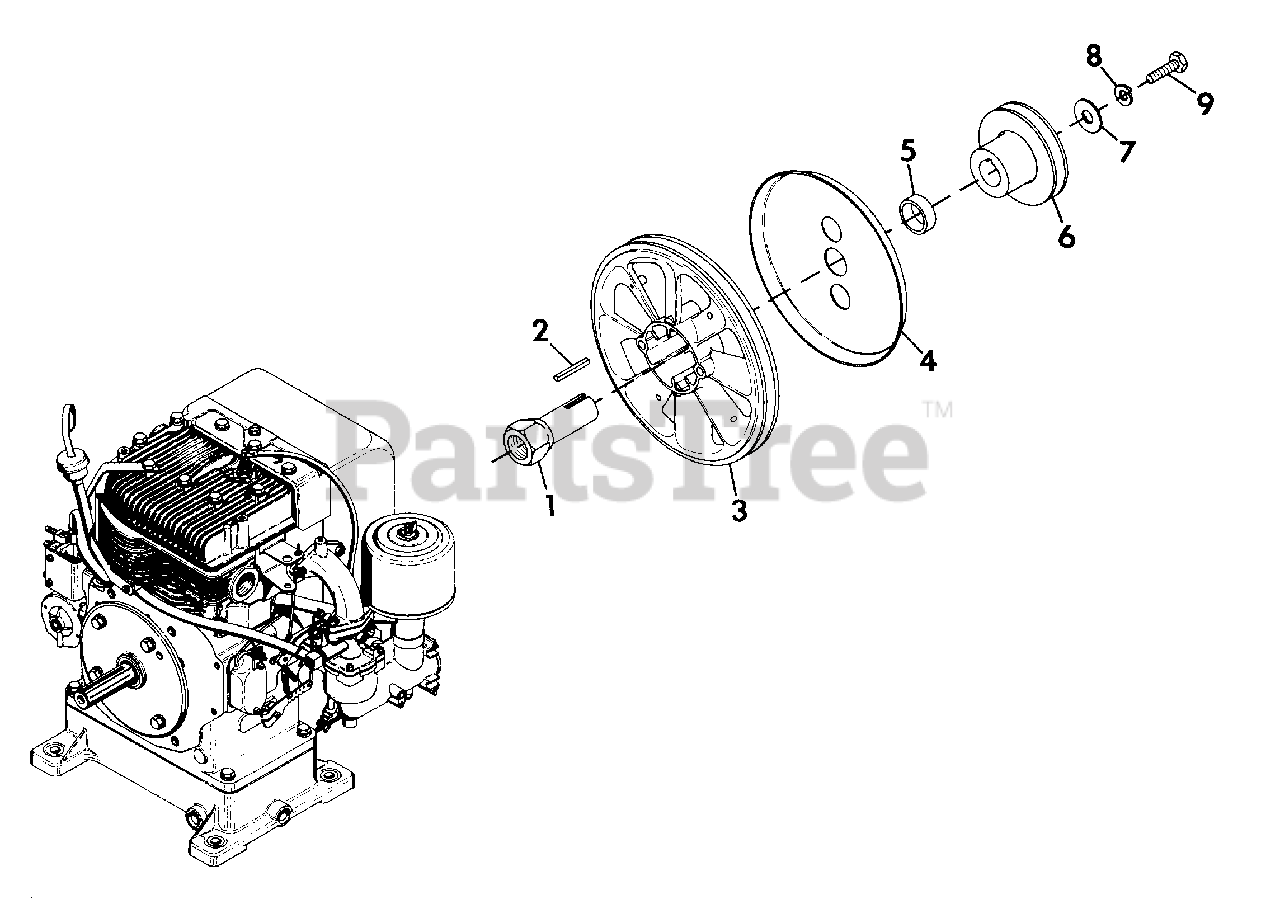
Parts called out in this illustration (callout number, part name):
1	ADAPTOR, DRIVE BRIGGS
2	KEY, SQUARE .250X1.250
3	FAN, AUXILIARY
4	SCREEN, GRASS BRIGGS
5	SPACER, PULLEY
6	SHEAVE, ENGINE
7	WASHER, FLAT 1.25X.50 HARD
8	WASHER, LOCK 7/16 REG.
9	BOLT, HEX 7/16-20X1.50
